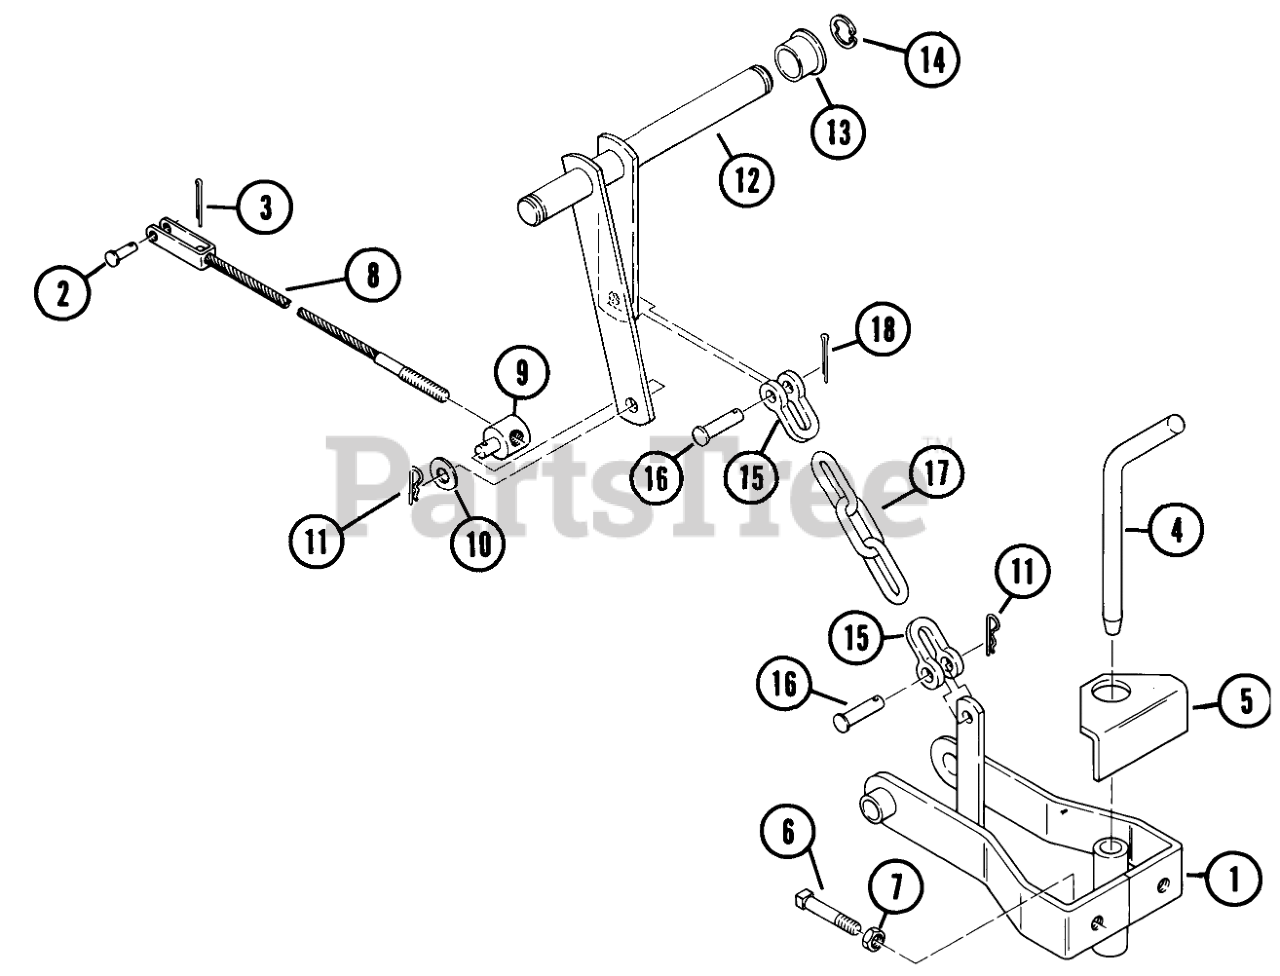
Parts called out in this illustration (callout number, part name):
1	Hitch Assembly
2	Pin
3	Cotter Pin
4	Hitch Pin
5	PLATE ADJ HITCH R
6	SCREW
7	Jam Nut
8	ASSY-LIFT CABLE
9	TRUNNION-CLUTCH ROD
10	Washer
11	Hairpin
12	Lever Assy.
13	BUSHING
14	E-RING
15	Clevis
16	Clevis Pin
17	Lift Chain
